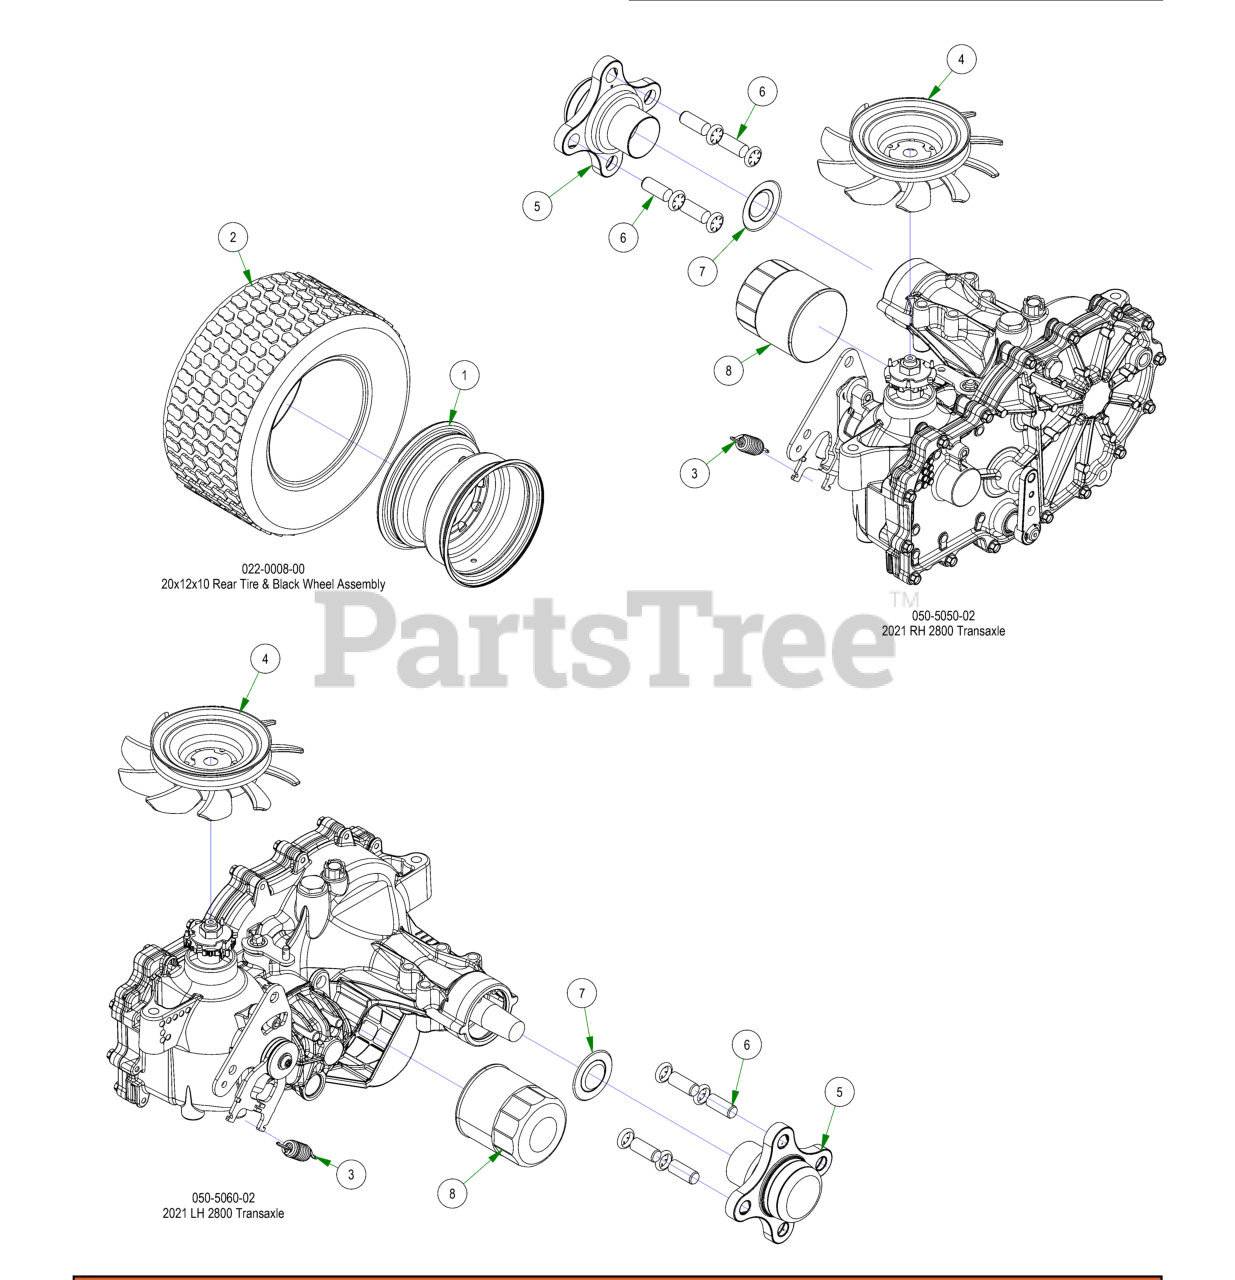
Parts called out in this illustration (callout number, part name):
1	10 x 8.50 Black Wheel for the 022-0008-00
2	20x12x10 Rear Tire
3	Gold Transaxle Spring
4	2021 ZT/Maverick Transaxle Fan/Pulley Kit
5	ZT Transaxle Wheel Hub
6	Transaxle Wheel Studs/ Drum Brake Studs
7	2021 ZT/Maverick Transaxle Seal Kit (ZT-2800)
8	ZT Hydraulic Filter
191	2024 EPA Build Date Punch Decal
192	Edge Clip With Ziptie
193	25/26 HP Koh Precleaner ZT/MZ
194	25/26 HP Koh Air Filter ZT/MZ
